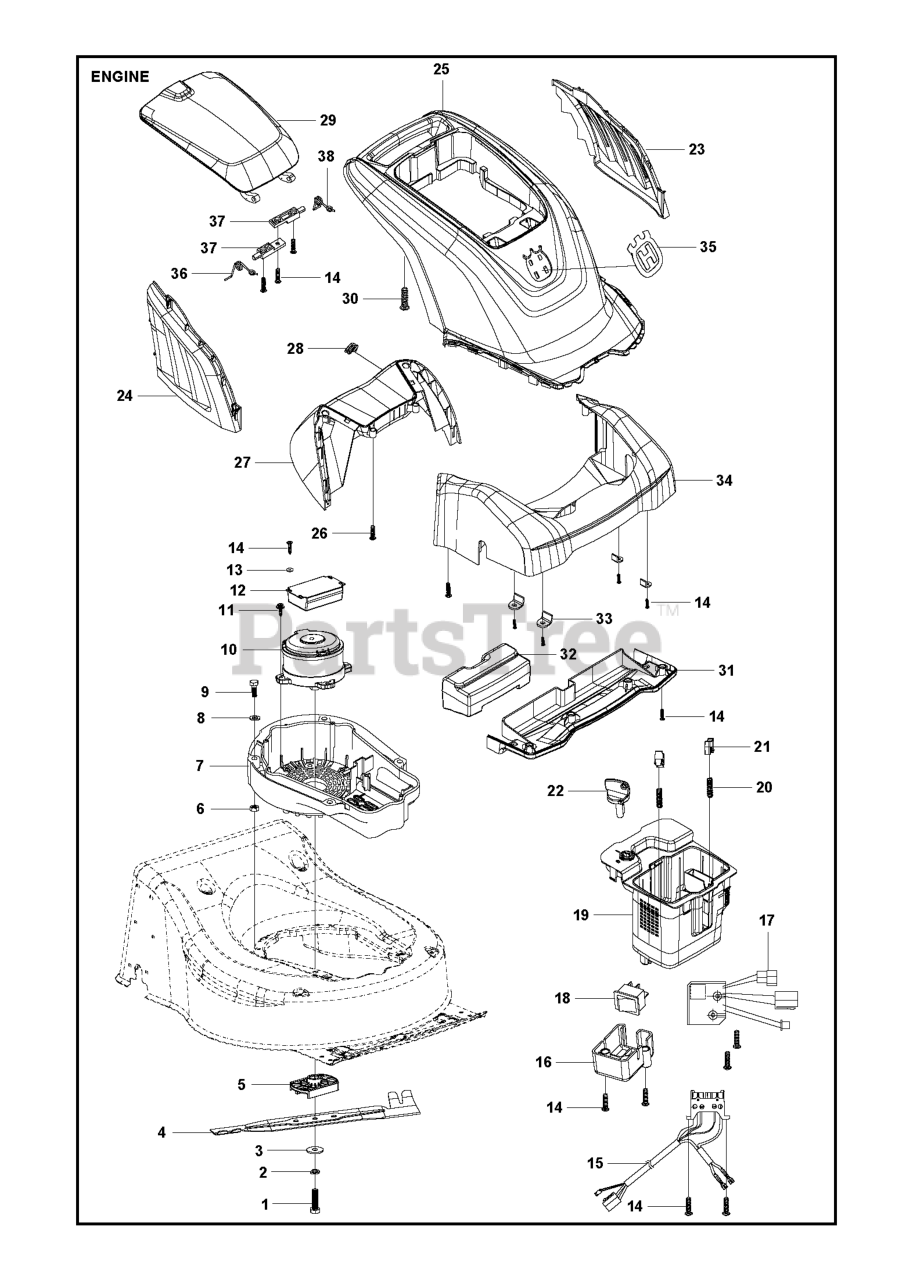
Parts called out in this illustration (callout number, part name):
2	SPRING WASHER
4	MOWER BLADE MULCH 40CM PRODUCT
5	BLADE SUPPORT
6	NUT LOCKING
15	WIRE BATTERY CONNECTOR
17	PRINTED CIRCUIT ASSY PUSH
18	KEY SWITCH
19	BOX BATTERY BOX
21	CAP COMPRESSION SPRING CAP
23	COVER LEFT AIR WINDOW PLATE
24	COVER RIGHT AIR WINDOW PLATE
25	COVER MOTOR COVER
27	COVER BACK COVER
29	COVER BATTERY LID
31	COVER FRONT HANDLE (UNDER SIDE
32	WEIGHT # 25100184101
34	COVER FRONT COVER
35	DECAL LOGO
36	TORSION SPRING
37	HINGE BATTERY LID HINGE
38	TORSION SPRING LEFT
